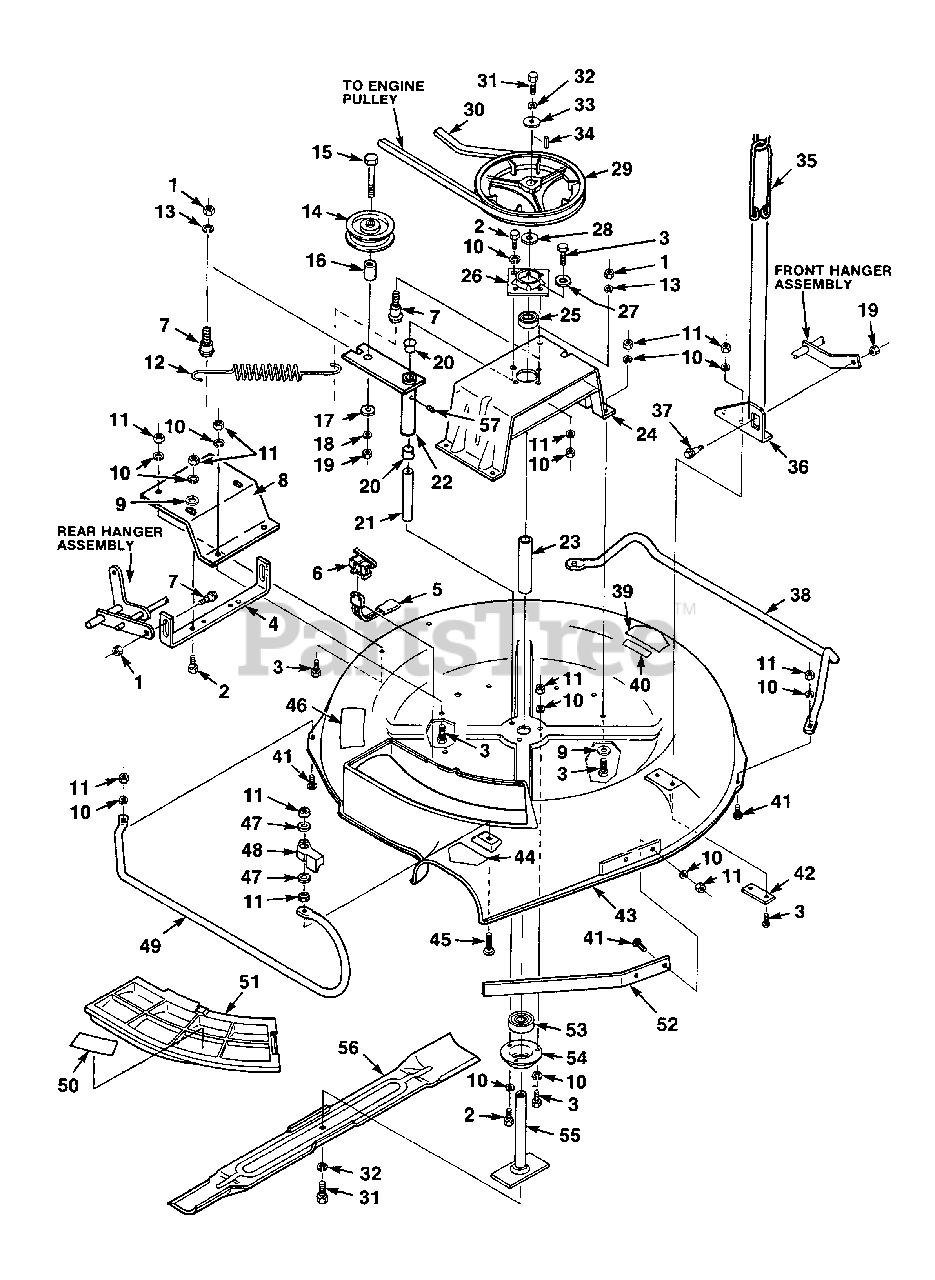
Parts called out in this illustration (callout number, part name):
1	NUT- Centerlock 5/16-18
2	SCREW- Cap hex hd. 1/4-20 x.750
3	SCREW- Cap hex hd. 1/4-20 x.625
4	BRACKET- Rear lift
5	DECK COVER SWITCH
6	BRACKET- Switch
7	BOLT- Shoulder 5/16-18
8	COWLING- Lower
9	WASHER- Flat 1/4
10	WASHER- Lock helical 1/4 long
11	NUT- Centerlock 1/4-20
13	WASHER- Helical 5/16
14	PULLEY- Idler
15	BOLT- Cap hex hd 1 3/8-16 x 2 1/2
17	WASHER- Flat 3/8
18	WASHER- Lock helical 3/8
19	NUT- Centerlock 3/8-16
20	BEARING- Flange
22	ARM- Pivot
23	SPACER- Spindle
24	BRACKET- Spindle
25	BEARING- Spindle
27	WASHER- Extruded
28	WASHER- Flat 3/4" special
29	PULLEY- Spindle
30	BELT- Mower
31	SCREW- Hex hd. 3/8-24 x 1
32	WASHER- Lock helical 3/8 hvy.
33	WASHER- Flat 3/8" special
35	LINK- Lower front lift
36	BRACKET- Front lift
37	BOLT- Shoulder 3/8-16 x 2.125
38	BAR- Skid (L.H.)
39	DECAL- CPSC warning
40	DECAL- No step
41	SCREW- 1/4-20 x 5/8 sq. nk. carr.
42	PLATE- Back up
43	DECK- Mower
44	DECAL- Danger
45	SCREW- Rd. hd. sq. nk. 1/4-20 x 1.25
46	DECAL- Danger
47	WASHER- Flat 1/4"
48	LATCH- Retaining
49	BAR- Skid (A.H.)
51	COVER- Plate
52	TOE GUARD
54	RETAINER- Bearing
55	SPINDLE & ADAPTOR
56	BAR- Cutter
57	GREASE FITTING
